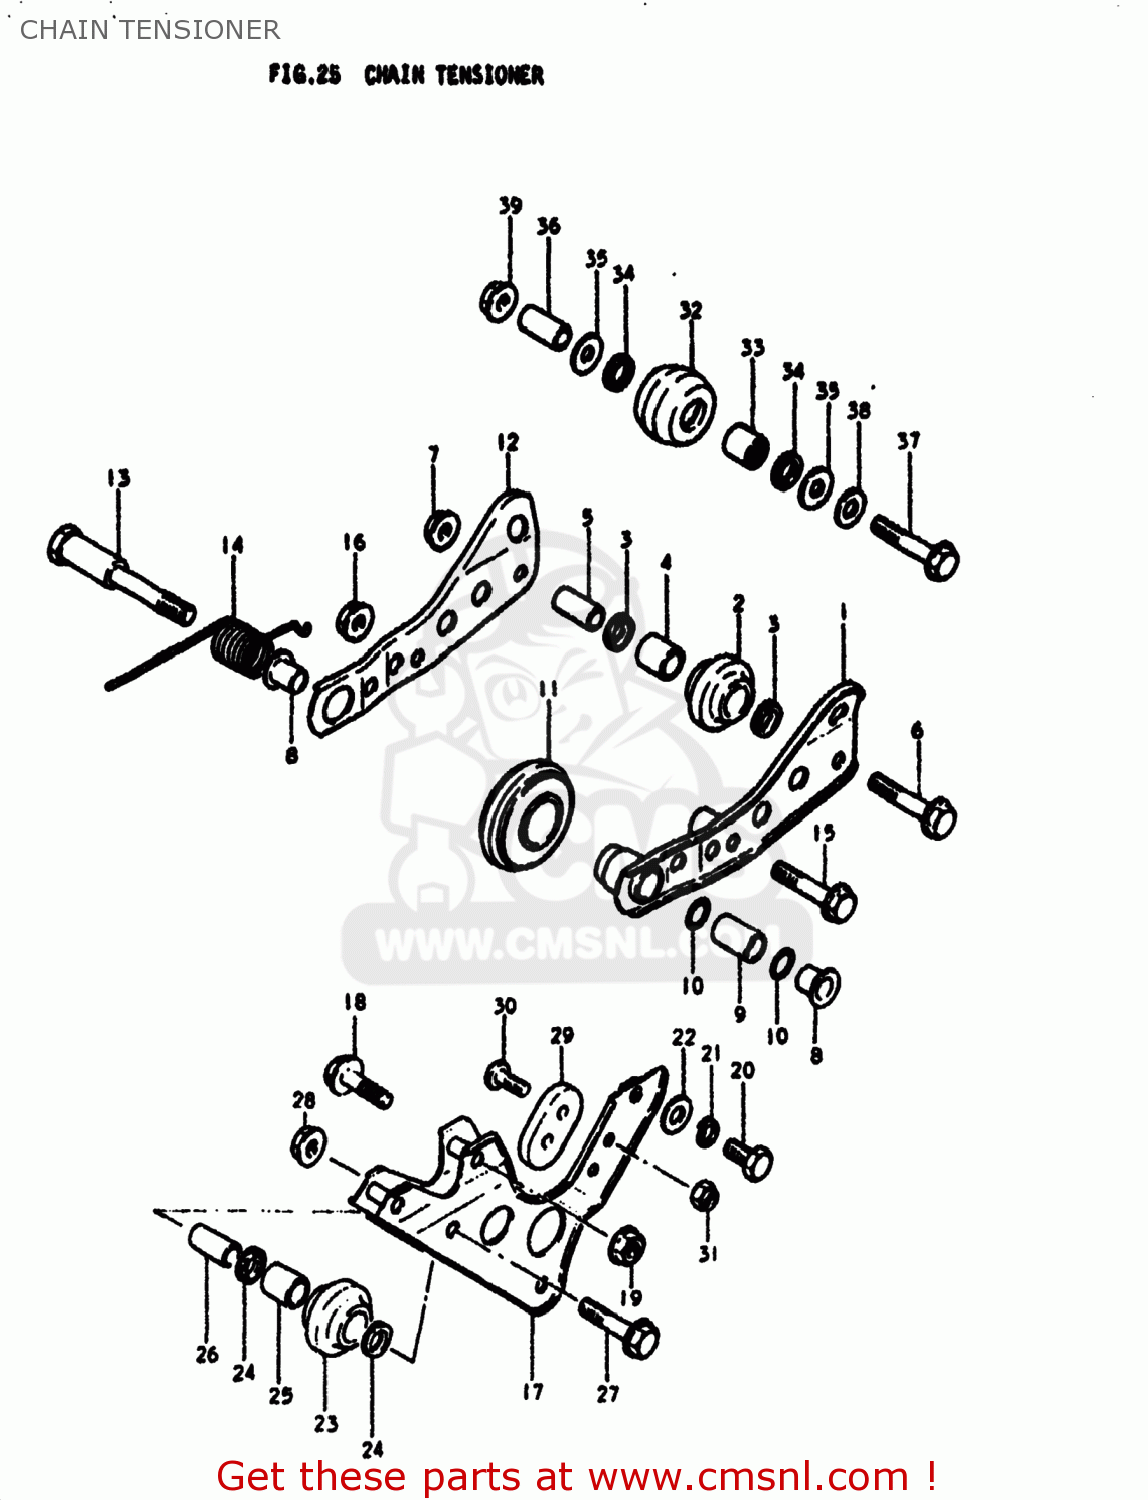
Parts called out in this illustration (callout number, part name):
1	TENSIONER,CHAIN
2	ROLLER,CHAIN TENSIONER LWR
3	SEAL,OIL(10X14.4X3.5)
4	SPACER,CHAIN GUIDE
5	SPACER(6.2X10X22.5)
6	BOLT 6X35
7	NUT
8	SPACER,CHAIN TENSIONER
9	BUSHING,CHAIN TENSIONER
10	O RING(D:1.3,ID:9.6)
11	ROLLER,CHAIN GUIDE
12	PLATE,CHAIN TENSIONER
13	BOLT
14	SPRING
15	BOLT 6X35
16	NUT
18	BOLT
19	NUT 6MM
20	BOLT(6X14)
21	LOCK WASHER
22	WASHER
23	ROLLER,CHAIN TENSIONER LWR
24	SEAL,OIL(10X14.4X3.5)
25	SPACER,CHAIN GUIDE
26	SPACER(6.2X10X22.5)
27	BOLT 6X35
28	NUT
29	PAD
30	SCREW
31	NUT
32	ROLLER,CHAIN GUIDE
33	BEARING(10X14X15)
34	SEAL,OIL(10X14.4X3.5)
35	WASHER(6.5X18X1)
36	SPACER(6.2X10X22.5)
37	BOLT
38	WASHER
39	NUT 6MM
